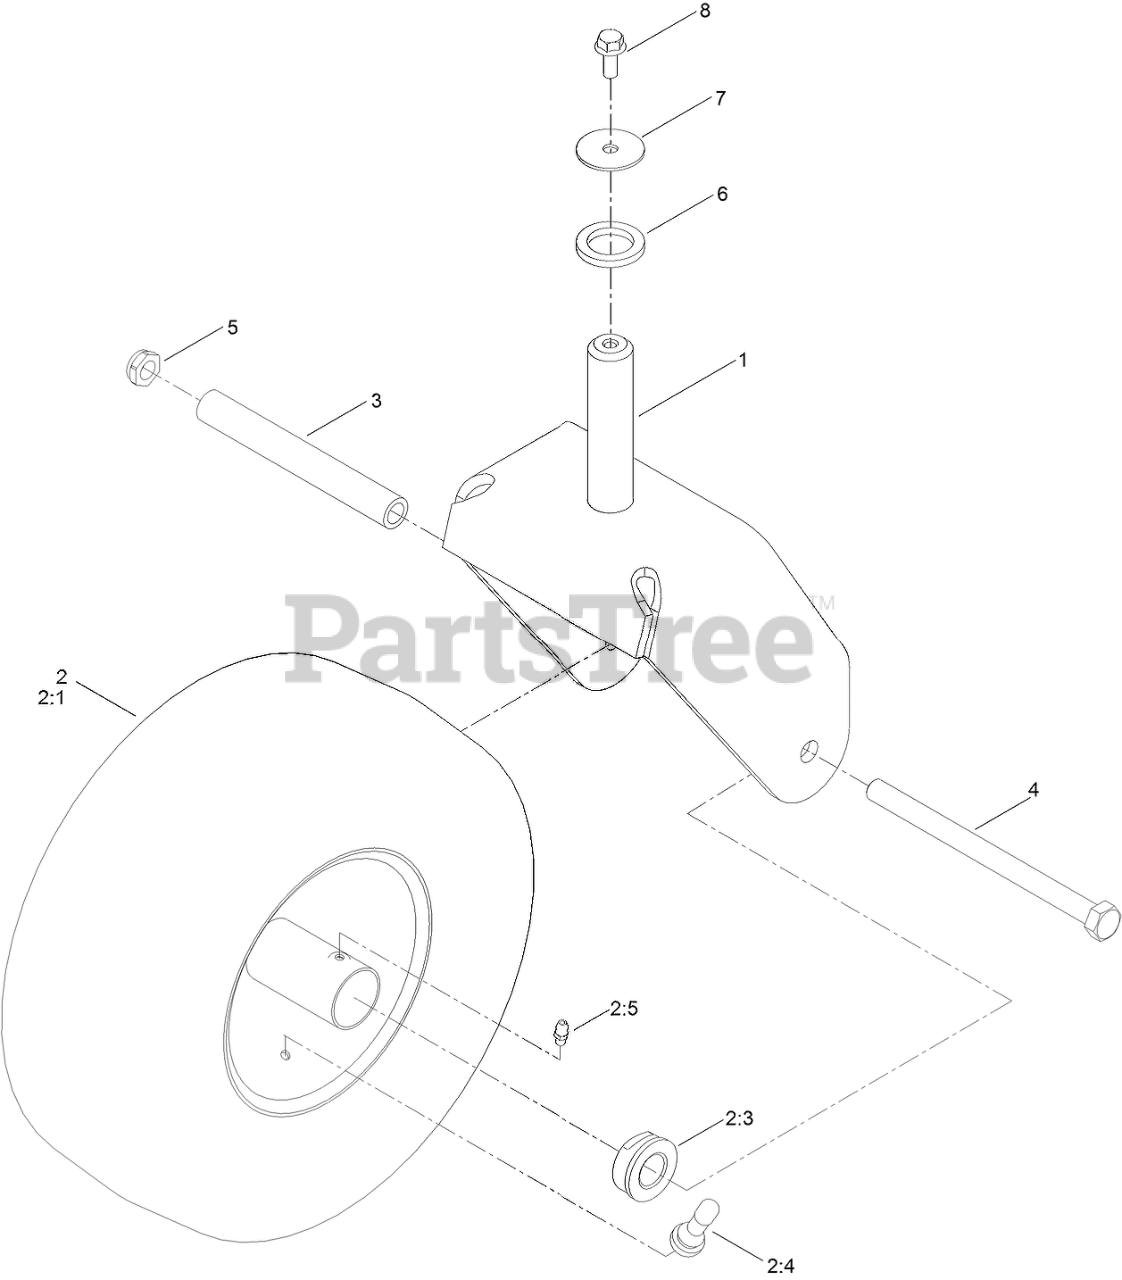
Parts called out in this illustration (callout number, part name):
1	FORK-CASTER
2	13 INCH WHEEL AND TIRE ASM
2:1	TIRE-13 INCH
2:3	BUSHING-FLANGE
2:5	FITTING-GREASE
3	BUSHING-SPANNER
4	SCREW-HH
5	NUT-LOCK, NI
6	WASHER-THRUST
7	WASHER-FLAT
8	SCREW-HHF
